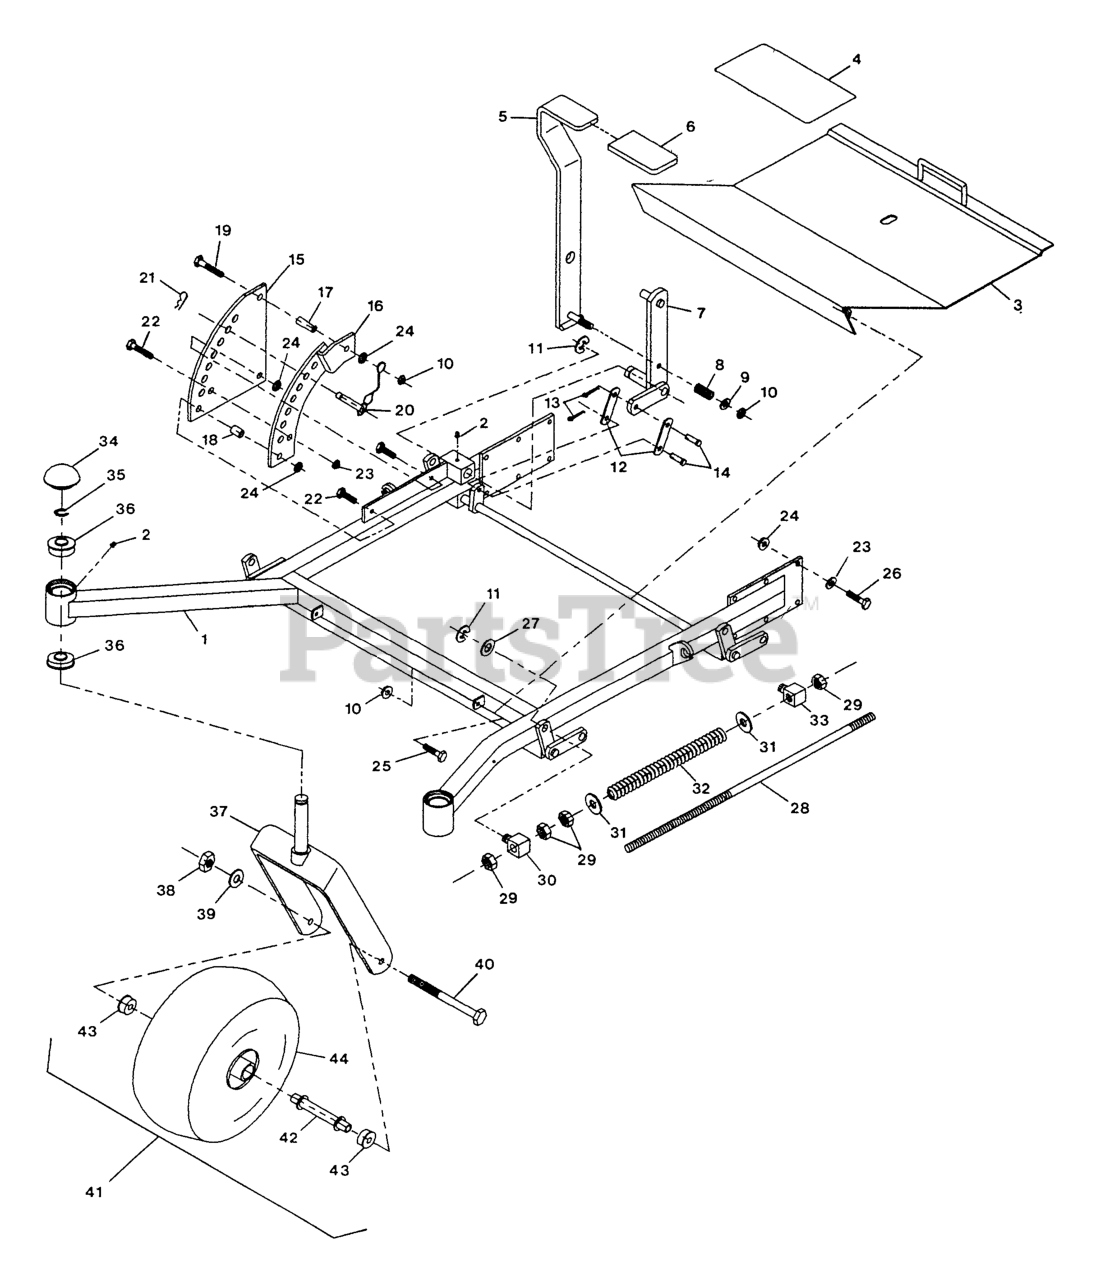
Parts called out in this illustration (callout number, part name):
4	PAD,ANTI SKID
6	GRIP-LEVER, LIFT
8	SPRING-COMPRESSION
12	ARM-LIFT, DECK
14	PIN-CLEVIS
17	BUSHING-LEVER, LIFT
18	BUSHING-LEVER, LIFT
20	PIN-HITCH (W/LANYARD)
21	PIN-COTTER
28	ROD-LIFT, DECK
30	SWIVEL-DECK MOUNT, REAR
32	SPRING-SUPPORT, DECK
34	CAP,GREASE
36	BEARING,FLANGED
37	WLD,CASTER
42	SPACER WLDMT-WHEEL
